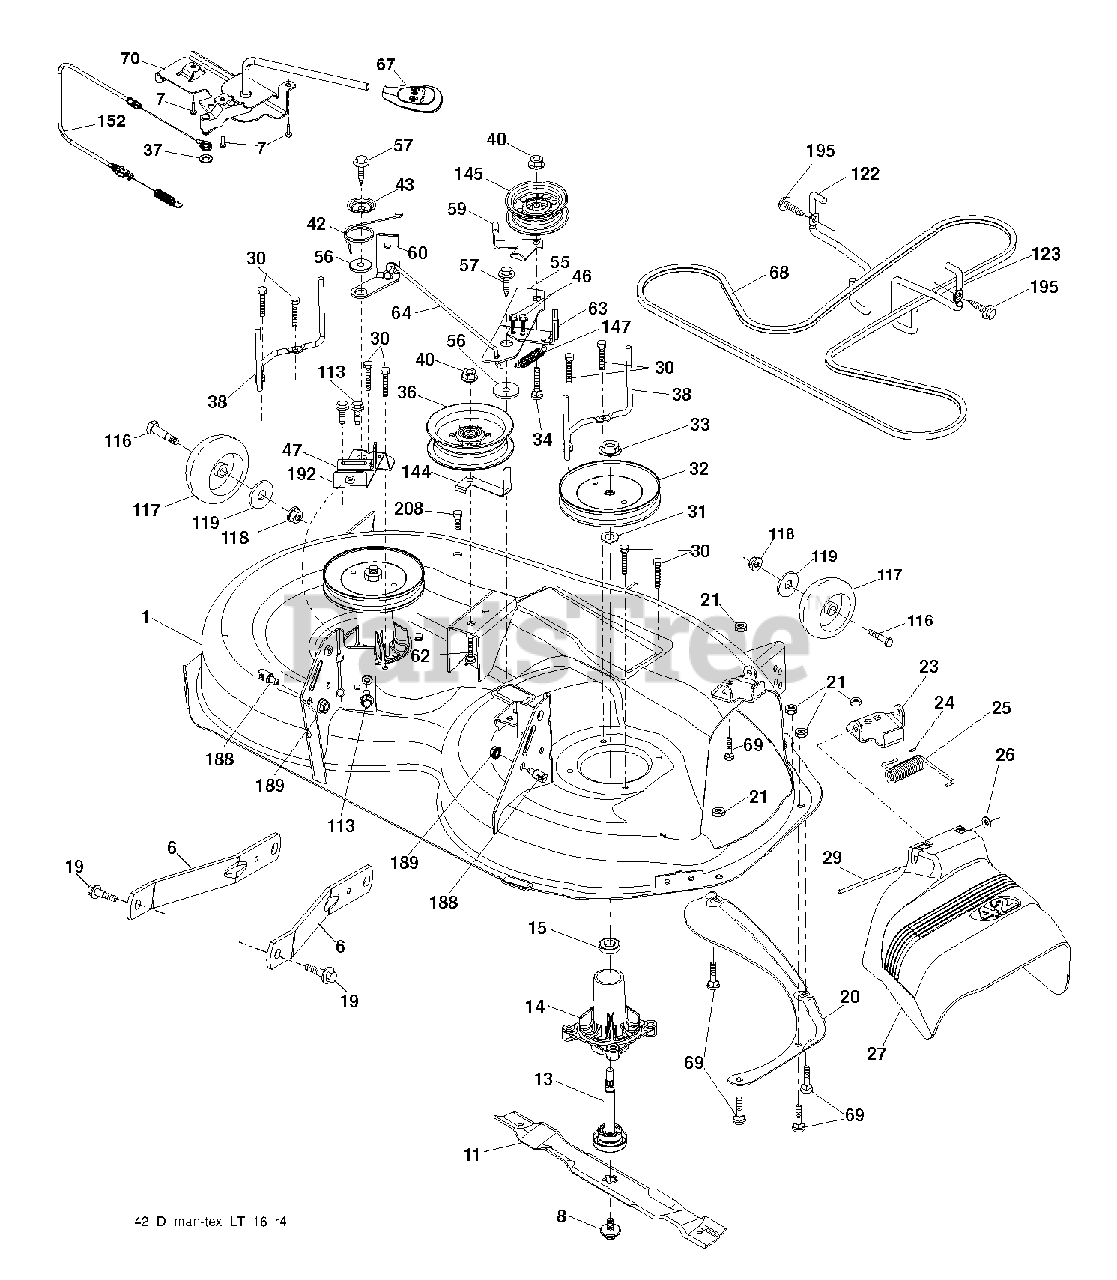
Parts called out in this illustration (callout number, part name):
1	DECK.WELDMENT.42"
6	ARM.SUSPENSION.MOWER.R
7	SCREW.#10 X 0.750.BOS THREAD
8	BOLT.WASHER.ASM.7/16-2
11	42" HI-LIFT BLADE
13	SHAFT.ASM.MDRL.N/GREASE.38
14	HOUSING MANDREL
19	BOLT.SHOULDER
20	BAFFLE.VORTEX
21	LOCKNUT
23	BRKT.DEFLECTOR.38"2005+
24	CAP-SLEEVE LT
25	SPRING.TORSION.DEFLECT
27	SHIELD.DEFLECTOR.MOWER.42"BLAC
29	ROD.HINGE
30	SCREW, WASHER HEAD
31	WASHER.SPACER.MANDREL
32	PULLEY.MANDREL.5.438.PD
33	NUT.FLANGE.LOCK.TOP
34	BOLT.3/8-16X1.50
36	PULLEY.IDLER.2006
38	KEEPER.BELT.MANDREL.PULLEY
40	NUT LOCK FLG 3/8-16 UNC
42	SPRING.TORSION.BRAKE
43	SRPING.TORSION.RETAINE
46	SCREW.1/4-20X5/8
47	BRKT.CLUTCH.CABLE
55	IDLER.ARM.42"
56	SPACER.RETAINER
57	SCREW 3/8-16X1
60	ARM BRAKE MOWER
62	BOLT
63	ARM BRAKE MOWER
64	LINK BRAKE
67	HANDLE.CLUTCH.CABLE.LT
68	BELT.DECK.DRIVE.42"
69	BOLT
70	CLUTCH.ASM.MANUAL.LT.TEX
113	BOLT.5/16HEX.WHS.HD
116	Shield Bolt, A 2.41 B 1.66
117	WHEEL.GAGE.HALF.SPOKED
118	NUT LOCK FLG 3/8-16 UNC
119	WASHER
122	KEEPER BELT ENGINE LH
123	KEEPER BELT RH
144	KEEPER.BELT.MOWER
145	PULLEY.IDLER.48"PRIMARY
147	RETURN SPRING
152	CABLE.CLUTCH.MANUAL.
188	STUD.FASTNER.W/ANTI-ROTATE
189	NUT LOCK HEX FLANGE 5/16-18
192	BRKT.BRAKE.STAND.LH.
195	SCREW, 3/8-16X3/4
208	SCREW 3/8-16X1/2
